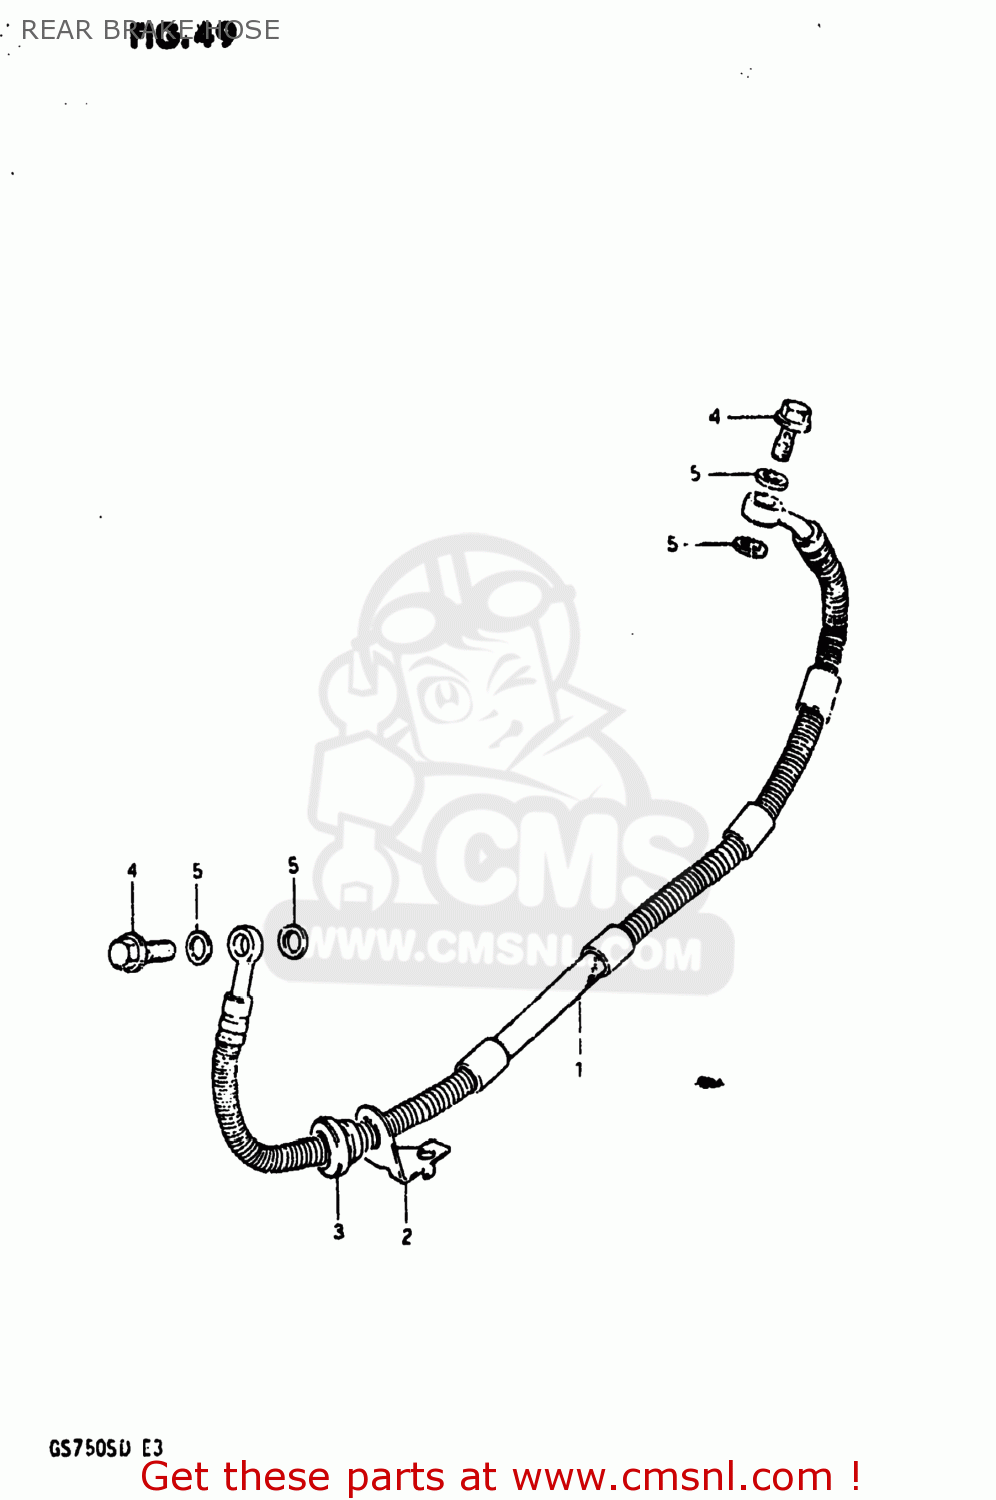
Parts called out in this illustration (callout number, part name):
1	HOSE,REAR BRAKE
2	GUIDE,BRAKE HOSE
3	GROMMET,BRAKE HOSE GUIDE
4	BOLT,UNION
5	WASHER
